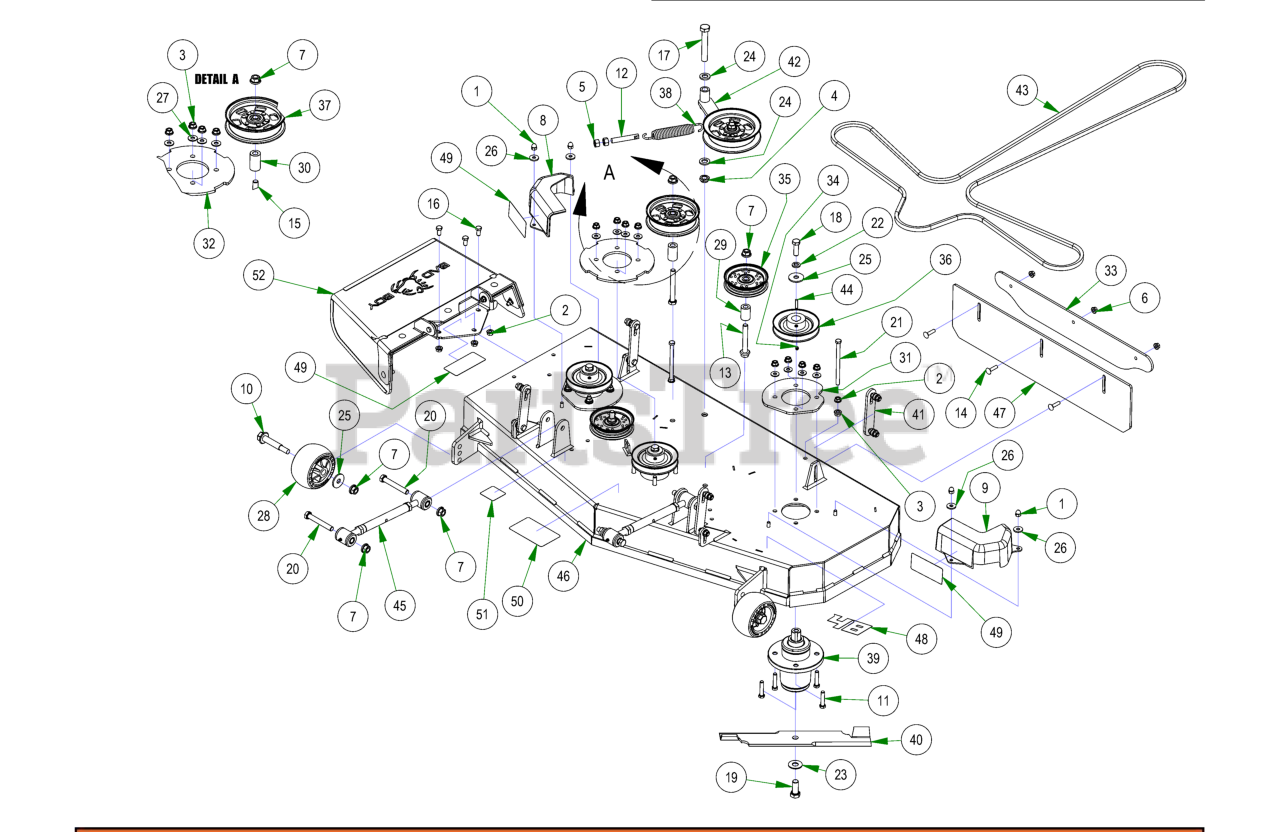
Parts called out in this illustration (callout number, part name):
1	5/16-18 ACORN NUT HIGH-CROWN ZC
2	3/8-16 HEX SERRATED FLANGE NUT HARD/ZINC
3	3/8-16 NYLON INSERT FLANGE LOCKNUT (GR.F) ZINC
4	5/8-11 NYLON INSERT JAM LOCKNUT ZINC
5	1/2-13 HEX NUT ZINC
6	5/16-18 NYLON INSERT FLANGE LOCKNUT ZINC
7	1/2-13 NYLON INSERT FLANGE LOCKNUT ZINC
8	pulley cover chute side
9	pulley cover non-chute side
10	Deck Wheel Bolt
11	3/8-16 X 1-3/4 HEX C/S (GR.5) ZC
12	All Thread
13	1/2-13 X 3-1/2 HEX FLANGE BOLT (GR.8) ZINC
14	5/16-18 X 1-1/4 CARRIAGE BOLT ZINC
15	1/2-13 X 4 HEX CAP SCREW (GR.8) ZINC YELLOW
16	3/8-16 X 3/4 HEX CAP SCREW (GR.5) ZINC
17	5/8-11 X 4 HEX CAP SCREW (GR.8) ZINC YELLOW
18	1/2-20 X 1-1/2 HEX CAP SCREW (GR.5) ZINC
19	5/8-18 X 1-1/2 HEX CAP SCREW (GR.8) ZINC YELLOW
20	1/2-13 X 3-1/2 HEX CAP SCREW (GR.5) ZINC
21	3/8-16 X 5-1/2 HEX CAP SCREW (GR.5) ZINC
22	1/2 SPLIT LOCKWASHER (GR.8) ZINC/YELLOW
23	5/8 USS FLAT WASHER (1-3/4" OD) GR.8 ZINC YELLOW
24	.635 ID X 1.120 OD X .140 THICK FLAT WASHER NYLON
25	1/2 BELLEVILLE WASHER (1-5/8 OD X .140 THK) ZINC
26	.360 ID X .983 OD X .120 THICK FLAT WASHER NYLON BLACK
27	5/16 USS FLAT WASHER (7/8 OD) ZINC
28	Deck Wheel
29	.502 ID X .750 OD X 1.500 Long Spacer
30	1 3/4" Pulley Spacer
31	42&48 Deck Spindle Support Plate
32	Deck Spindle Support Plate
33	2023 4" & 5" Stripping Kit Plate
34	5/16-24 X 1/4 SOCKET SET SCREW (CUP PT) PLAIN
35	4 3/4 Idler Pulley - ABFI-76
36	5" Spindle Deck Pulley
37	5-3/4 Idler Pulley
38	Deck Idler Spring
39	OUTLAW SPINDLE ASSEMBLY
40	48" ZT/Mav/Compact Outlaw Blade with Fusion
41	Deck Hanger Assembly
42	2017 MZ/ZT Deck Idler Assembly
43	B147 Deck Belt
44	1/4 X 1 SQ MACHINERY KEY 1018 STL PLN
45	2018 Maverick Turnbuckle (Top Link)
46	2023 48" x 5" Deck
47	2023 ZT Stripping Kit Rubber
48	48" Deck Decal
49	Danger Decal-Spindle/Discharge
50	Deck Belt Route Decal
51	Deck Impact Patent Decal 9591803
52	ZT Chute Assembly
